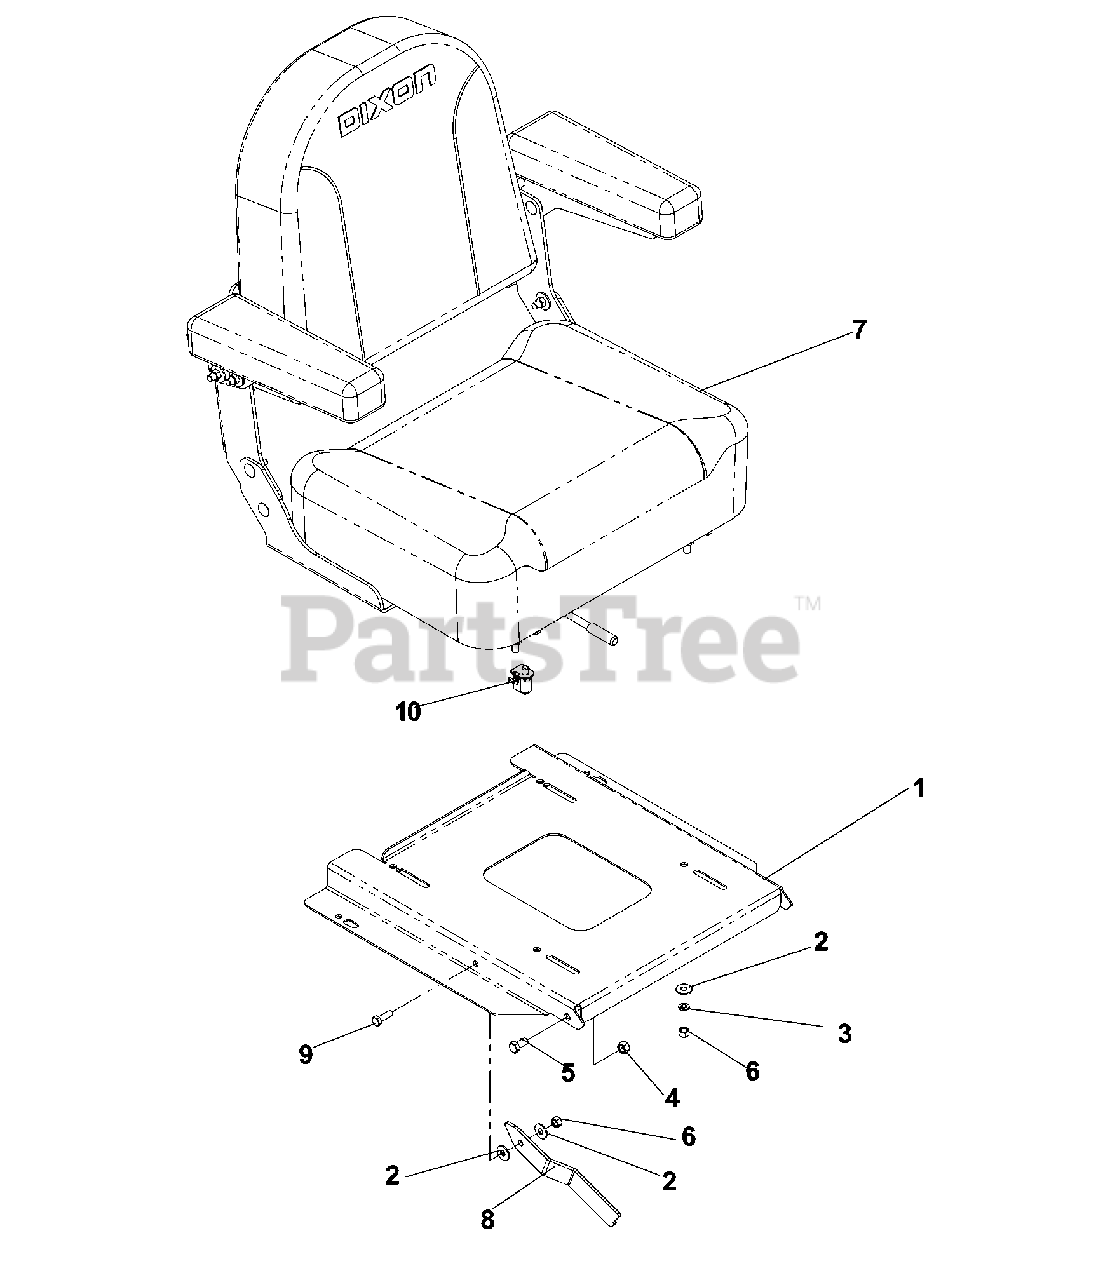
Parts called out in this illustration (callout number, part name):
1	PAN, SEAT
2	WASHER 5/16 FLAT
3	WASHER 5/16 LOCK
4	NUT 3/8-16 NYLOC
5	SCREW 3/8C X 3/4 HEX CAP
6	NUT 5/16 NYLOC
7	SEAT ASM W/SLIDE
8	ARM, PROP, SEAT
9	HCS 5/16C X 1
10	SEAT SWITCH
